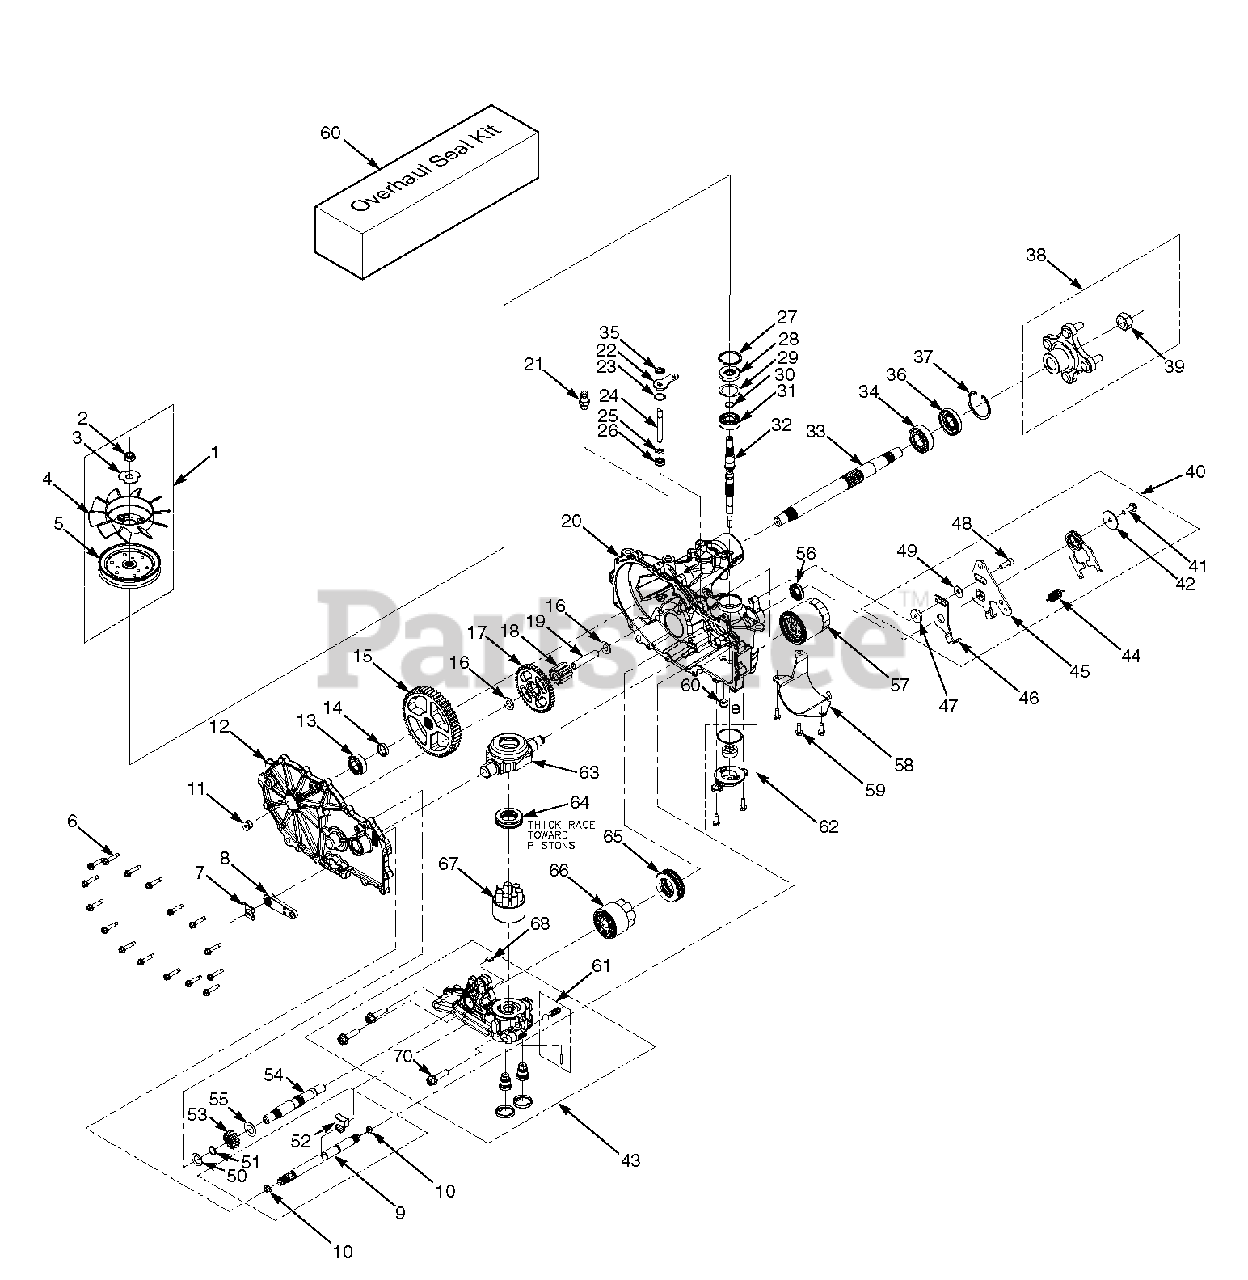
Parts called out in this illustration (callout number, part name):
1	Kit, Fan & Pulley
2	Nut, Hex Locking 1/2-20
3	Washer, Slotted
4	Fan, 7" Dai.
5	Pulley, Cupped 4-1/2" Dia
5	Hub, Pulley
6	Bolt, Hex Head 1/4-20 x 1-11/4"
7	Clip, Retaining
8	Handle, Brake
9	Shaft, Brake
10	O-Ring
11	Plug, 9/16-18
12	Kit, Side Cover RH
13	Bearing, Ball .75 x 40 x 12
14	Spacer, .75 x 1.0 x .257
15	Gear, 54T
16	Washer, .5 x 1.0 x .03
17	Gear, 43T
17	Gear, 45T
18	Gear, 11T
19	Jackshaft Pin
20	Kit, Housing RH
21	Fitting
22	Arm, By-Pass
23	Ring, Retaining .750 Internal
24	Rod, By-Pass
25	Ring, .Retaining .375 External
26	Seal, Lip .375 x .75 x .25
27	Ring, Retaining 2.06 Internal
28	Seal, Lip 17 x 40 x 7
29	Washer, 1.23 x 1.56 x .04
30	Ring, Retaining Wire
31	Bearing, Ball 17 x 40 x 12 Open
32	Shaft, Input
33	Shaft Kit, Axle
34	Bearing, Ball 1.0 x 52 x 15 Open
35	Ring, Retainging .375 External
36	Seal, Lip 25 x 52 x 10 TC Gray
37	Ring, Retaining 2.06 Internal
38	Hub Kit
39	Nut, Hex Locking
40	Kit, RTN Assembly
41	Bolt, 5/16-24 x 1" Patch
42	Washer, .343 x 1.5 x .062
43	Kit, Center Section RH
44	Spring
45	Arm, Control
46	Arm, Neutral RH
47	Spacer, .320 x 1.005 x .179
48	Bolt, 5/16-24 x 1" Patch
49	Washer, .34 x .88 x .06
50	Washer, .63 x 1.0 x .05
51	Ring, Retaining
52	Pawl, Brake
53	Gear, 16T
53	Gear, 14T
54	Shaft, Motor
55	Washer, .72 x 1.16 x .04
56	Seal, Lip 18 x 32 x 7
57	Filter
58	Filter Guard
59	Bolt, 1/4-20 x 3/4"
60	Seal Kit
61	Kit, Charge Relief
62	Kit, Charge Pump
63	Trunnion Swashplate
64	Thrust Bearing
65	Thrust Bearing
66	Kit, Motor Cylinder Block
67	Kit, Cylinder Block
68	Plate, By-Pass
69	Kit, Charge Relief
70	Bolt, Hex Head 3/8-16 x 1-1/2" Patch
